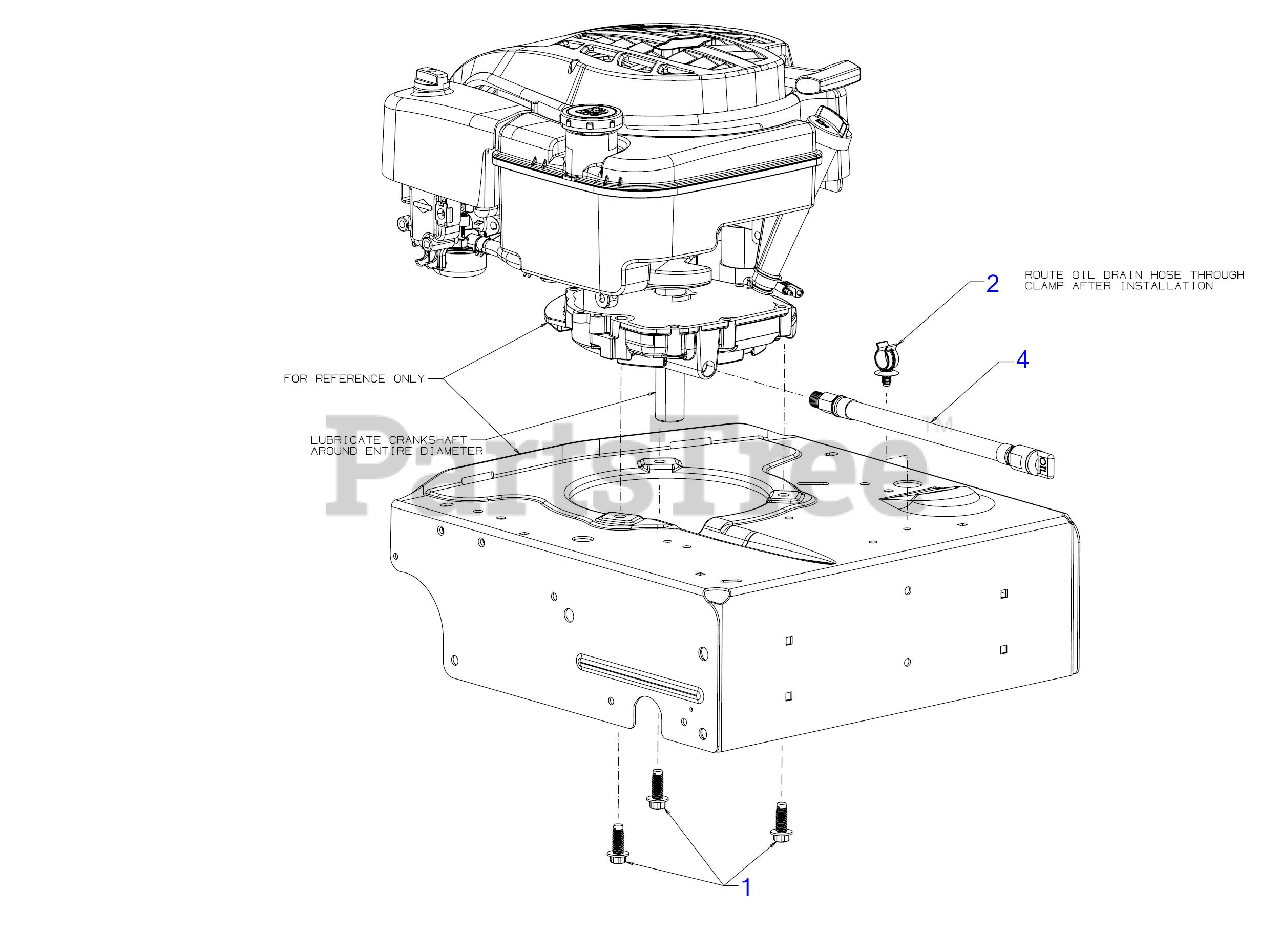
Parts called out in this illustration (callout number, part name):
1	SCREW 3/8-16 x 1
2	DRAIN HOSE CLIP
4	OIL DRAIN HOSE 1/4 NPT
